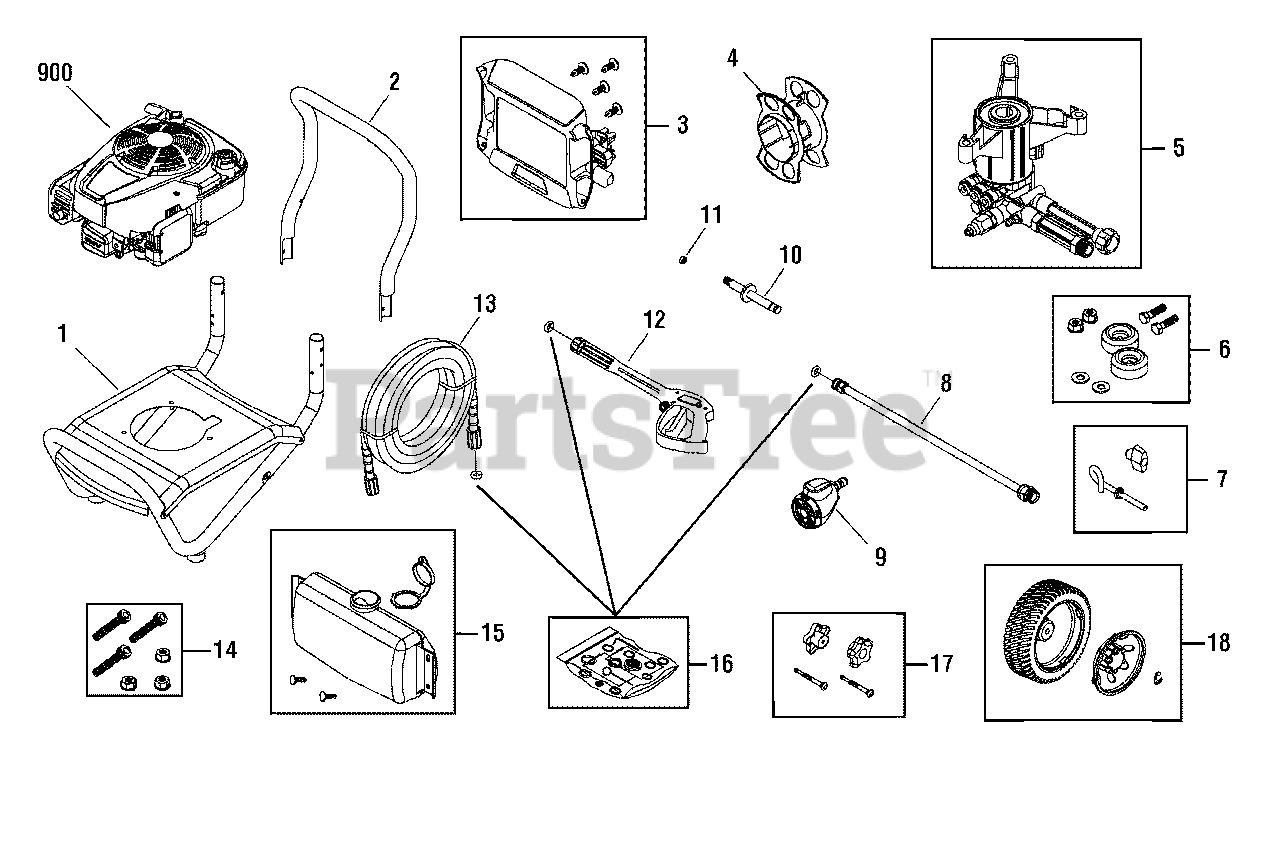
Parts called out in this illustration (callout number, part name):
6	MOUNT, Vibration
8	EXTENSION, QC
9	NOZZLE, QC
10	AXLE
11	NUT
12	GUN
14	KIT, Hardware, Pump Mounting
16	KIT, O-Ring
17	KIT, Hardware, Handle
18	KIT, Wheel
900	* ENGINE
